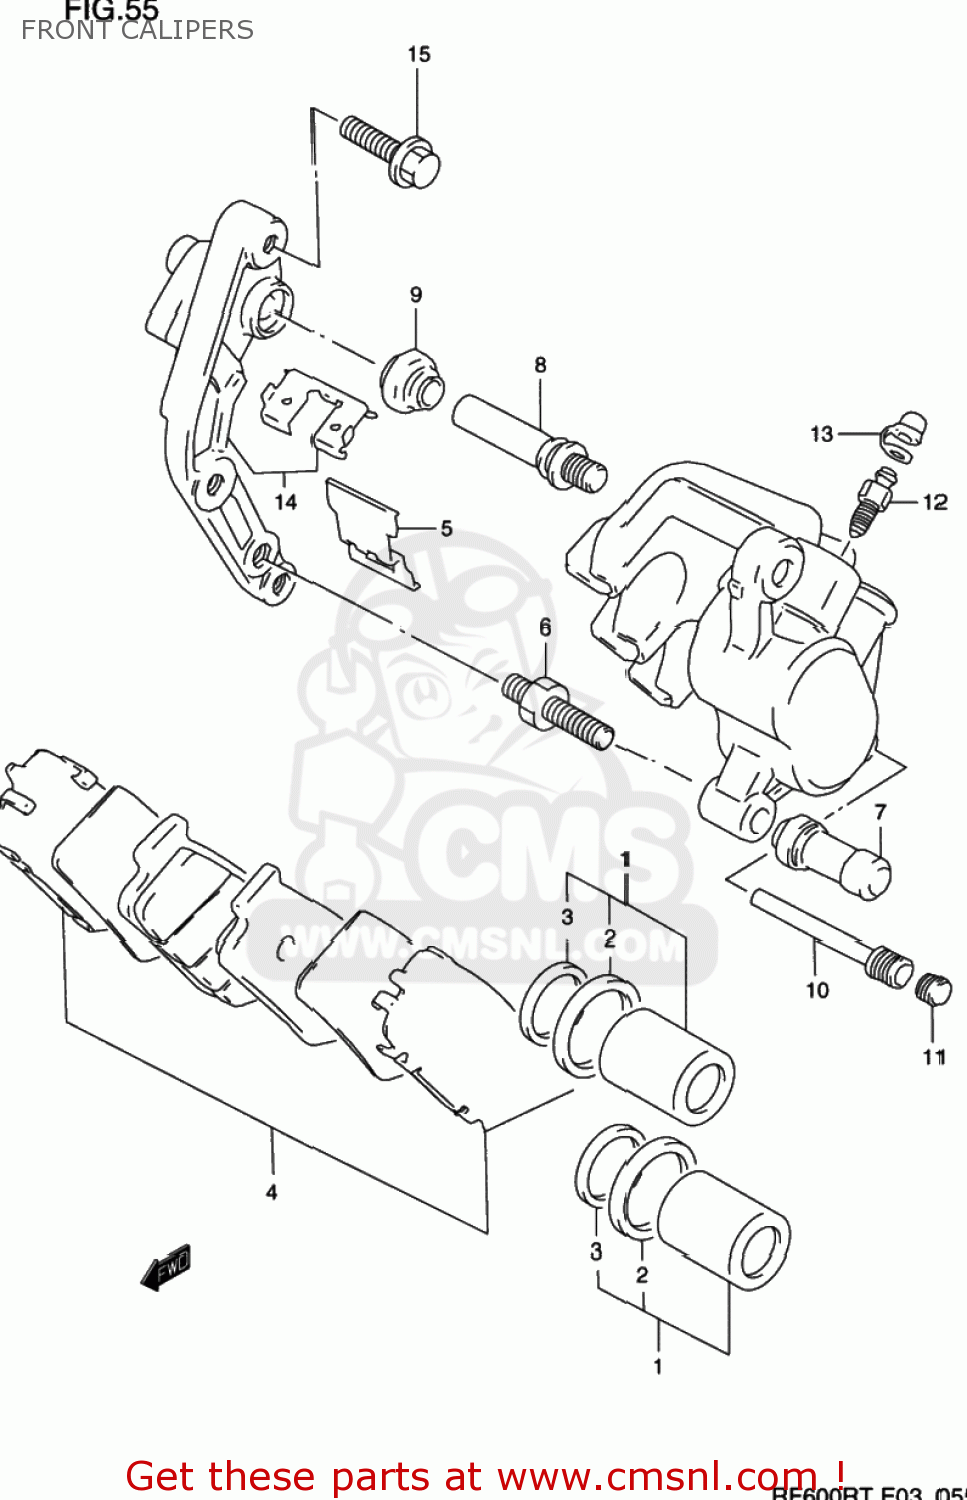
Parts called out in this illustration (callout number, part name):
1	PISTON SET
2	SEAL,PISTON
3	SEAL,DUST
4	PAD & SHIM SET (NAS)
5	SPRING,PAD
6	PIN,BOLT
7	BOOT
8	PIN
9	BOOT
10	PIN,HANGER
11	PLUG,PIN
12	BLEEDER
13	CAP,BLEEDER
14	BRACKET,R
15	BOLT(8X30)
